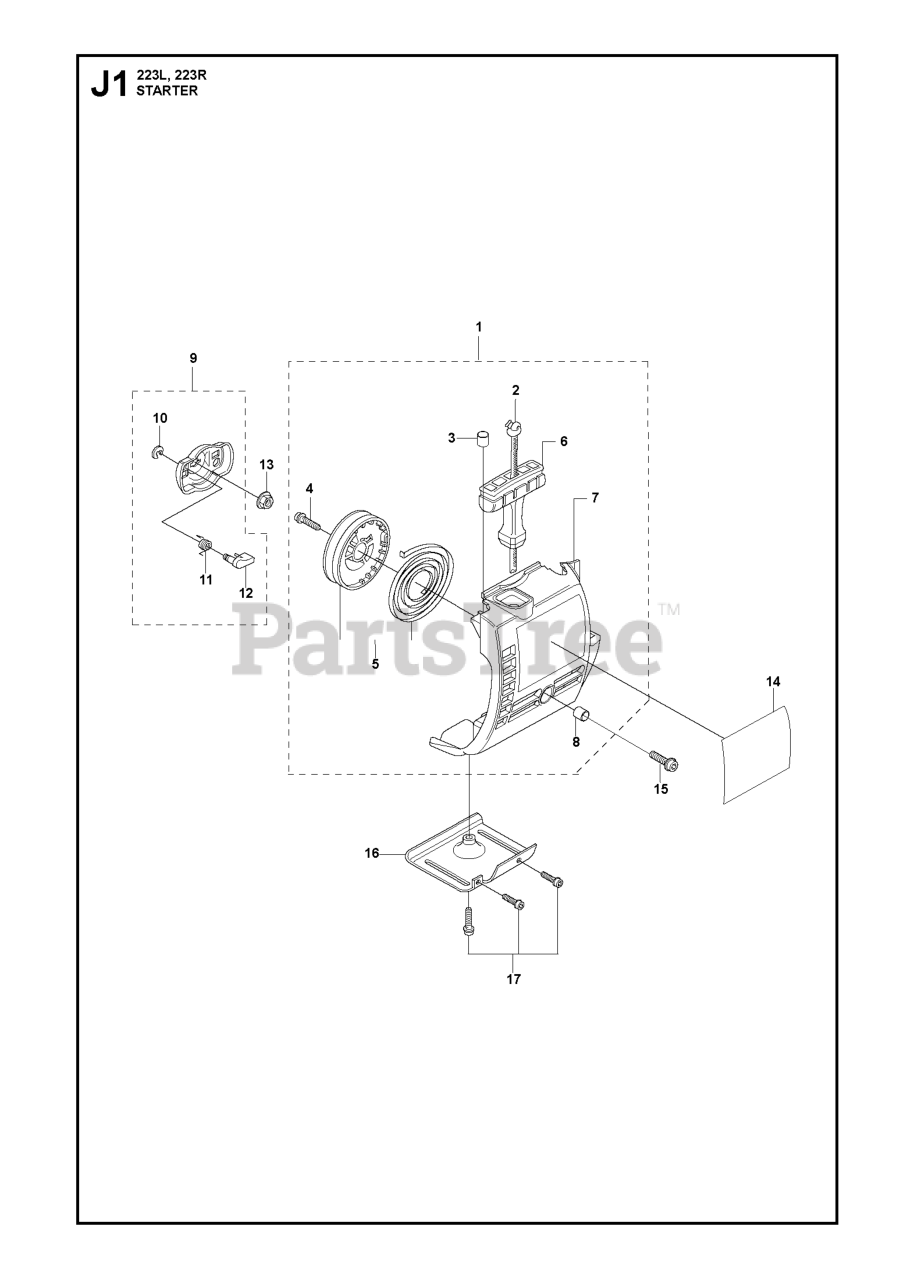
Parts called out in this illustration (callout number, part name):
1	STARTER DEVICE
2	STARTER ROPE
3	%SPACER SLEEVE
5	STARTER PULLEY ASSY.
6	STARTER HANDLE
7	RP STARTER HOUSING
8	%SPACER SLEEVE
9	PAWL ASSY COMPLETE
12	STARTER PAWL
13	FLANGE NUT
14	223 STARTER HOUSING DECAL
14	LABEL STARTING DEVICE
16	PLATE
